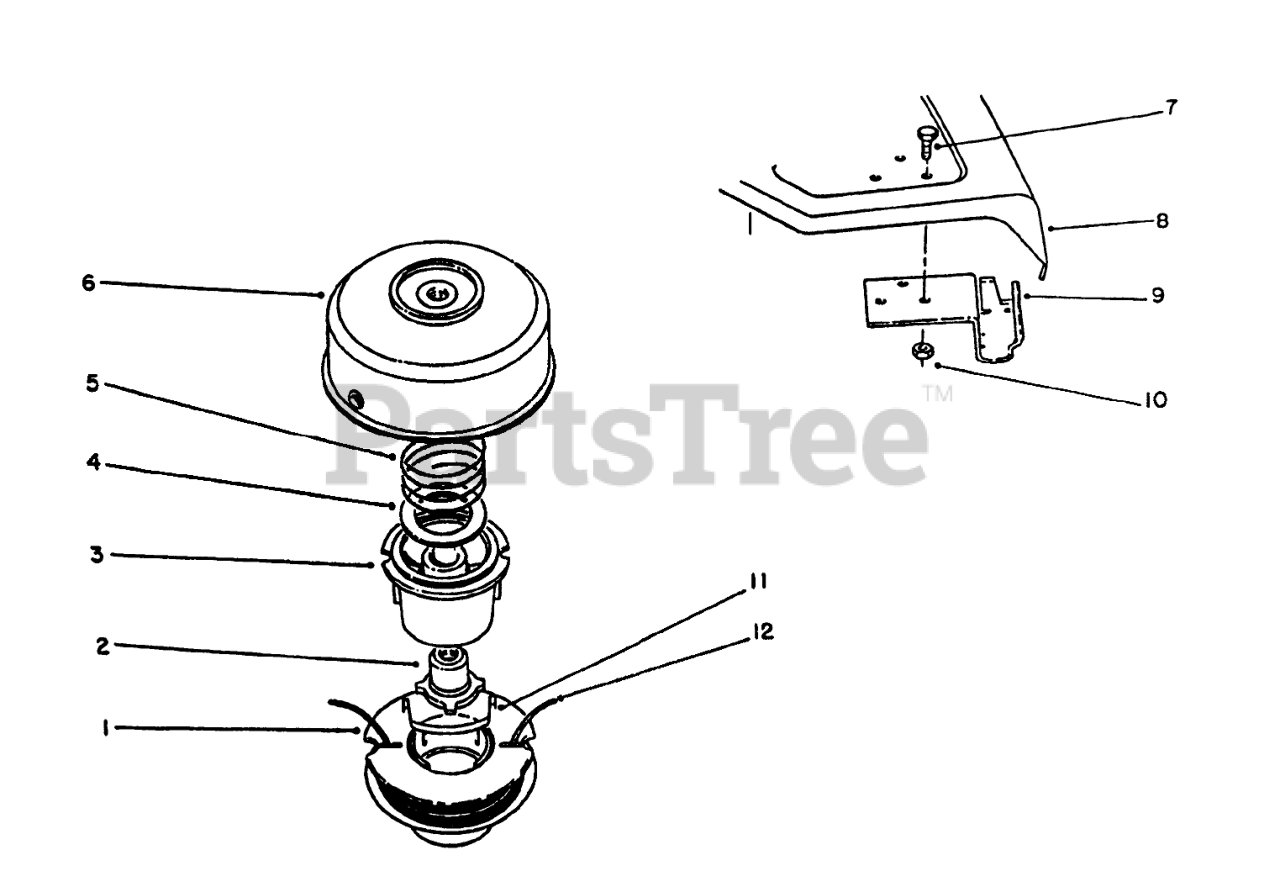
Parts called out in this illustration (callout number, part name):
1	Spool Prewound .08 Dia.38- (Incl.Ref.#11 & 12)
2	LH DRIVER
3	SPOOL CORE
4	WASHER-FLAT
5	SPRING
6	ASM - TRIMMER DRUM & EYELET
7	SCREW-SHH
8	Shield-Grass
9	BRACKET & KNIFE ASM
10	NUT-LOCK, NI
11	SADDLE-SPOOL CAP
